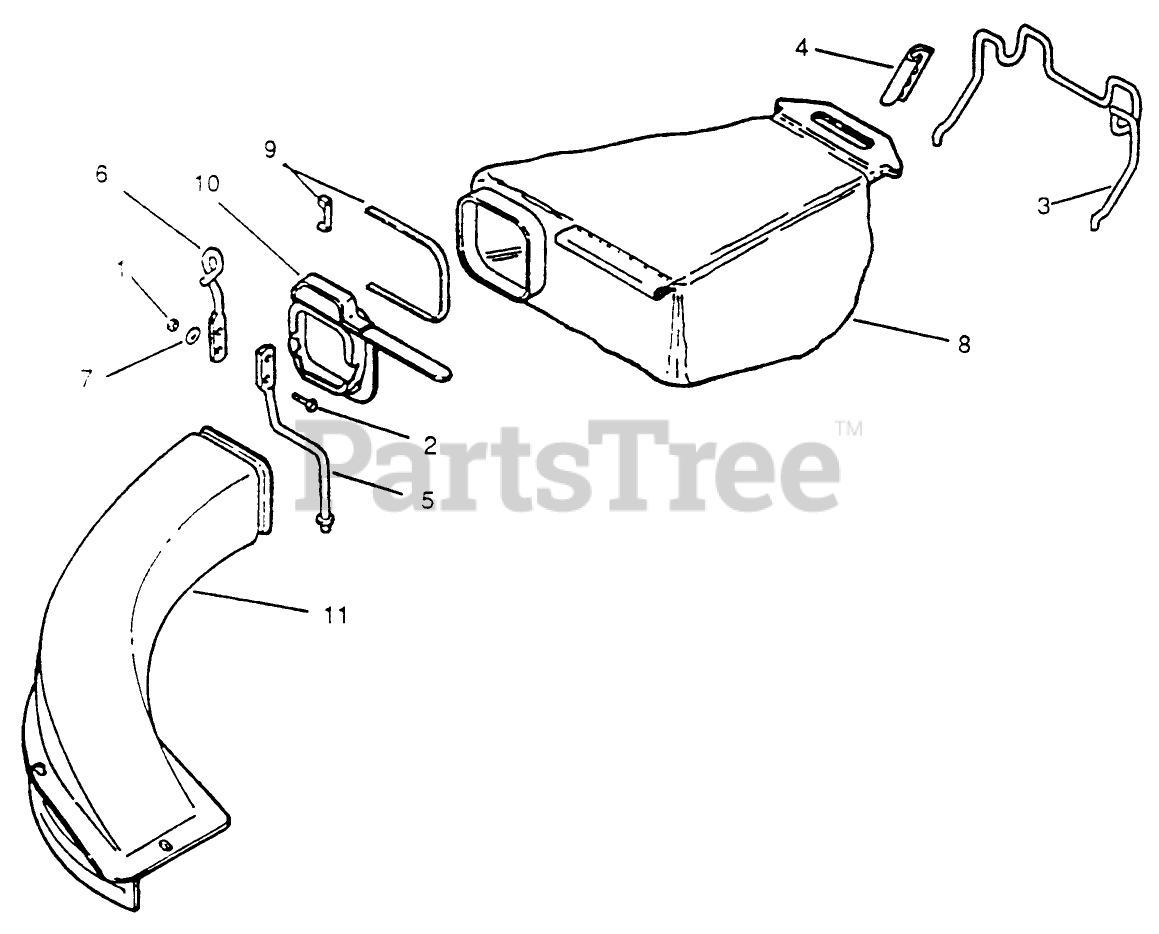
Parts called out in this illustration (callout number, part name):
1	LOCKNUT E
3	HANGER-WIRE
11	REAR CATCHR CHUTE
